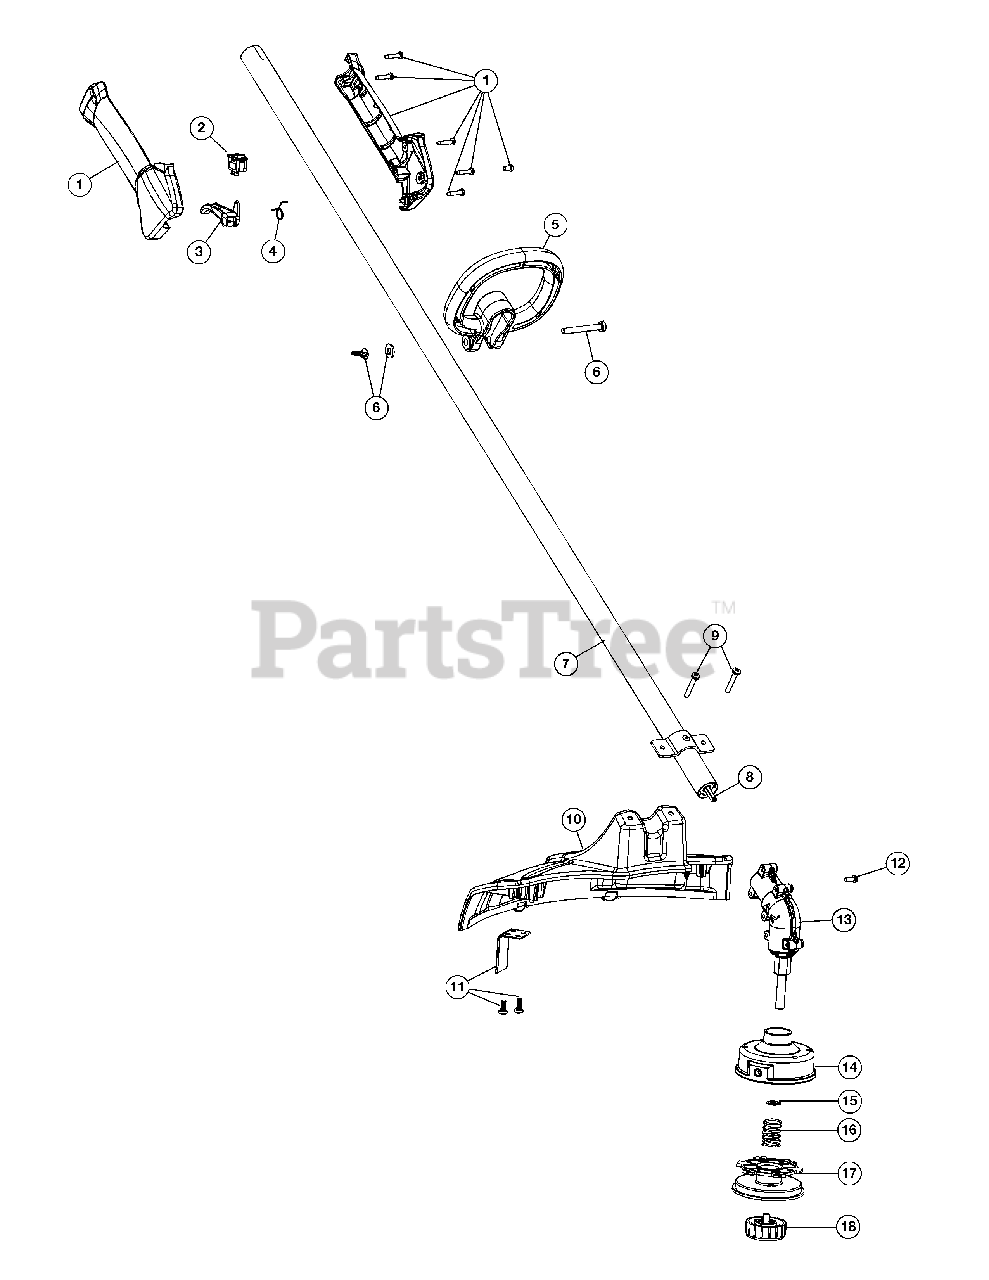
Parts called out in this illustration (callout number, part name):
1	Throttle Housing Assembly (Incl. 2 - 4)
3	Throttle Trigger
4	Throttle Trigger Spring
5	D-Handle (Incl. 6)
6	D-Handle Hardware Assembly
7	Drive Shaft Housing Assembly (Incl. 8)
8	Flexible Drive Shaft
9	Shield Mounting Screw
10	Shield Assembly (Incl. 9 & 11)
11	Blade Assembly
12	Anti-Rotation Screw
13	Gearbox Assembly (Incl. 14 - 18)
14	Outer Spool Assembly (Incl. 15)
15	Retainer
17	Inner Reel
18	Bump Head Knob Assembly
